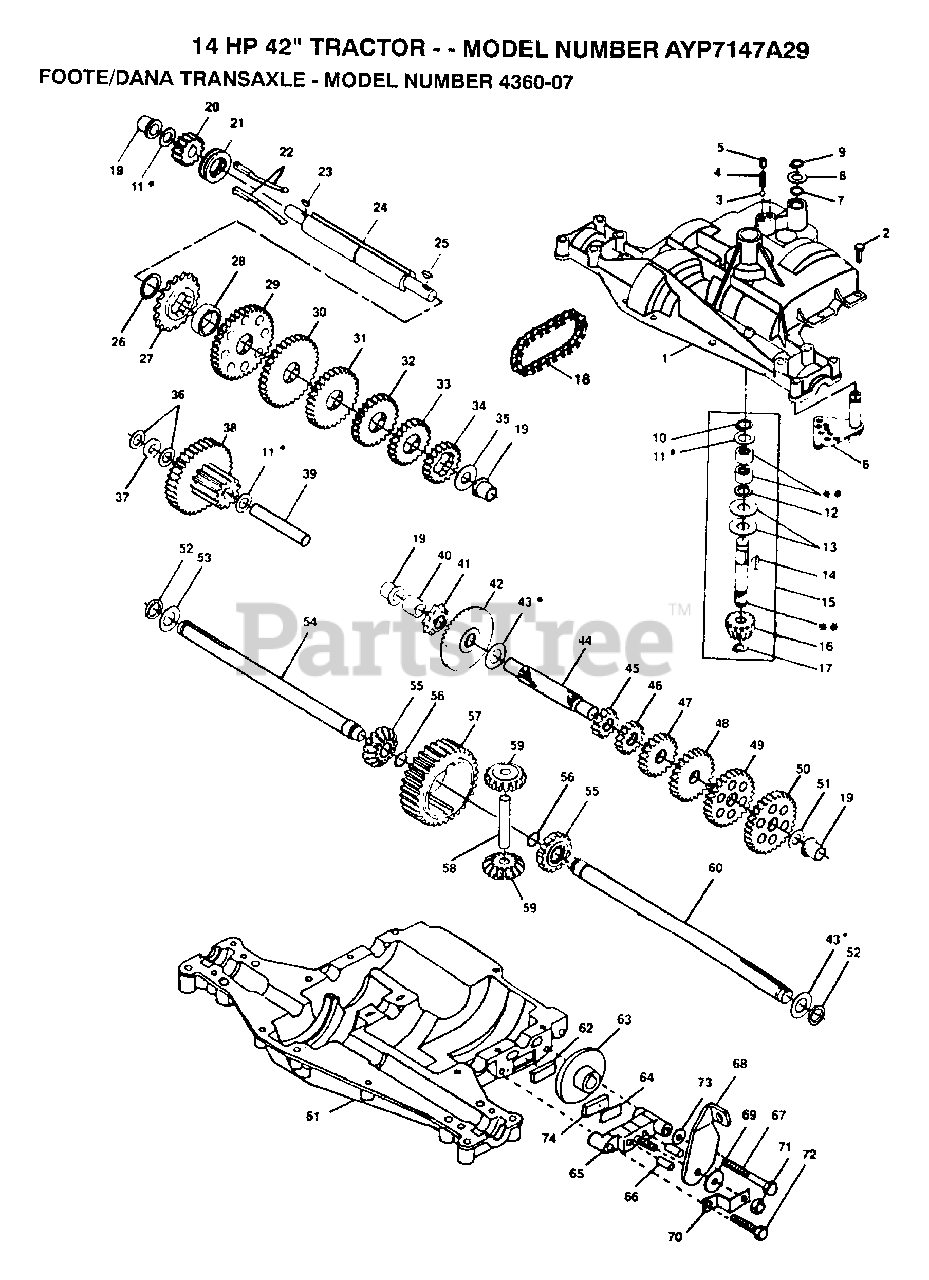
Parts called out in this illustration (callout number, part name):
1	HOUSING UPPER
3	BALL DETENT
4	SPRING, DETENT
5	SCREW, SET
6	ASSY SHIFTER
8	WASHER PLAIN
9	RING RETAINING
10	RING RETAINING
11	WASHER PLAIN
13	WASHER, PLAIN .632 X 1.38 X .046
14	KEY WOODRUFF #9
15	ASSY KIT INPUT SHAFT
16	PINION, BEVEL, 14 TEETH
17	RING, RETAINING
18	CHAIN, 24 PITCHES
19	BEARING, FLANGE
20	GEAR SPUR, 14 TEETH
21	COLLAR CLUTCH
22	KEY CLUTCH
23	KEY WOODRUFF #3
24	SHAFT INTERMEDIATE
25	KEY, WOODRUFF, #61
26	RING, RETAINING
27	SPROCKET, 18 TEETH
29	GEAR, SPUR, 37 TEETH
30	GEAR, SPUR, 35 TEETH
31	GEAR, SPUR, 30 TEETH
32	GEAR, SPUR, 25 TEETH
33	GEAR, SPUR, 22 TEETH
35	WASHER, PLAIN .640 X 1.37 X .061
36	WASHER, PLAIN .632 X 1.00 X .026
37	SPACER .630 X 1.00 X .169
38	ASSY GEAR COMB 12&35 TEETH
39	SHAFT IDLER
40	SPACER .635 X .875 X .755
41	SPROCKET, 9 TEETH
42	GEAR, BEVEL, 42 TEETH
43	WASHER PLAIN
44	SHAFT, DRIVE
45	GEAR, SPUR, 12 TEETH
46	GEAR SPUR, 15 TEETH
47	GEAR, SPUR, 20 TEETH
48	GEAR, SPUR, 25 TEETH
49	GEAR, SPUR, 28 TEETH
50	GEAR, SPUR, 31 TEETH
51	WASHER, PLAIN .632 X 1.00 X .060
53	WASHER PLAIN
54	AXLE LEFT HAND
55	GEAR, MITER, 15 TEETH
56	RING, RETAINING
57	GEAR, SPUR, 32 TEETH
58	SHAFT, CROSS
59	GEAR, MITER, 15 TEETH
60	AXLE, R.H.
61	HOUSING LOWER
62	PUCK, FRICTION
63	DISC, BRAKE
65	JAW, BRAKE
66	PIN, DOWEL
67	SCREW TAPPING
68	LEVER, ACTUATING
69	WASHER, PLAIN .321 X 1.00 X .055
70	BRACKET, ANTI-ROTATION
71	LOCKNUT 5/16-24
72	SCREW TAPPING
73	WASHER PLAIN
74	PUCK, FRICTION
